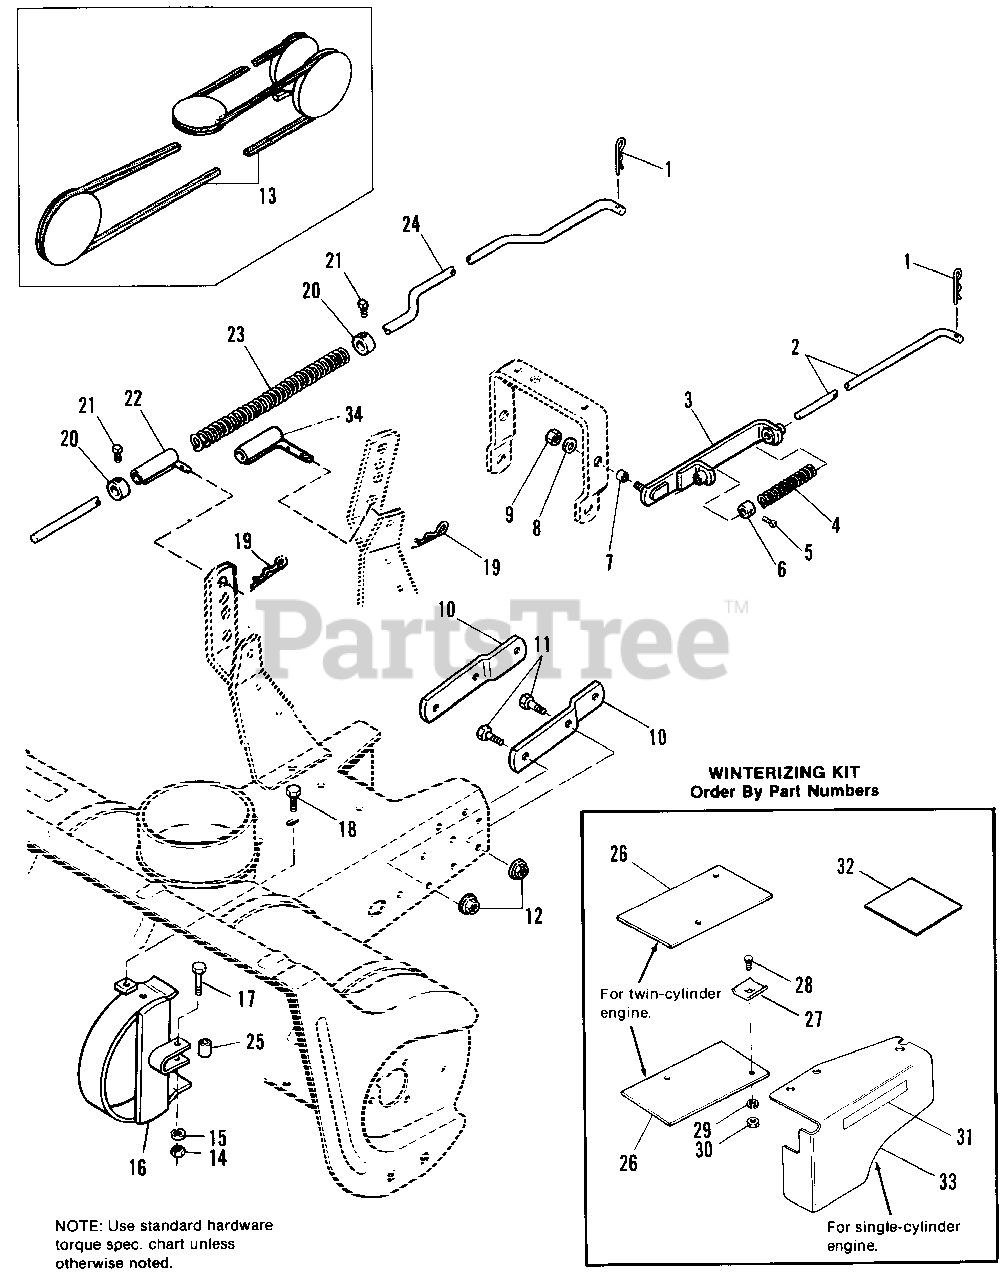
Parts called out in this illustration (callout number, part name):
1	CLIP, Spring
3	GUIDE ASSY., Rod
5	SETSCREW, 1/4-20 x 3/8
6	COLLAR, Set
8	WASHER, Plain, 5/16
9	LOCKNUT, Hex, Jam, 3/8-16
10	CLIP, Frame
11	CAPSCREW, Hex, 7/16-14 x 1
12	LOCKNUT, Hex, Flange, 7/16-14
13	V-BELT (Drive)
14	NUT, Hex, Full, 5/16-18
15	LOCKWASHER, 5/16
16	GUARD ASSY., Belt
17	CAPSCREW, Hex, 5/16-18 X 1-1/4
18	SCREW, Self-Tping, 5/16-18 x 1/2
19	CLIP, Spring
20	COLLAR, Set
21	SETSCREW, 5/16-18 x 1/2
22	GUIDE ASSY., Rod, (1692239 only)
26	HOOD, w/louvers (for twin-cylinder engines)
28	CARRIAGE BOLT, 1/4-20 X 5/8
29	LOCKWASHER
30	NUT, Hex, Full, 1/4-20
31	DECAL, Shield
32	DECAL, Installation (under hood)
33	DEFLECTOR (for single-cylinder engines)
34	GUIDE ASSY., (1690556 Only)
